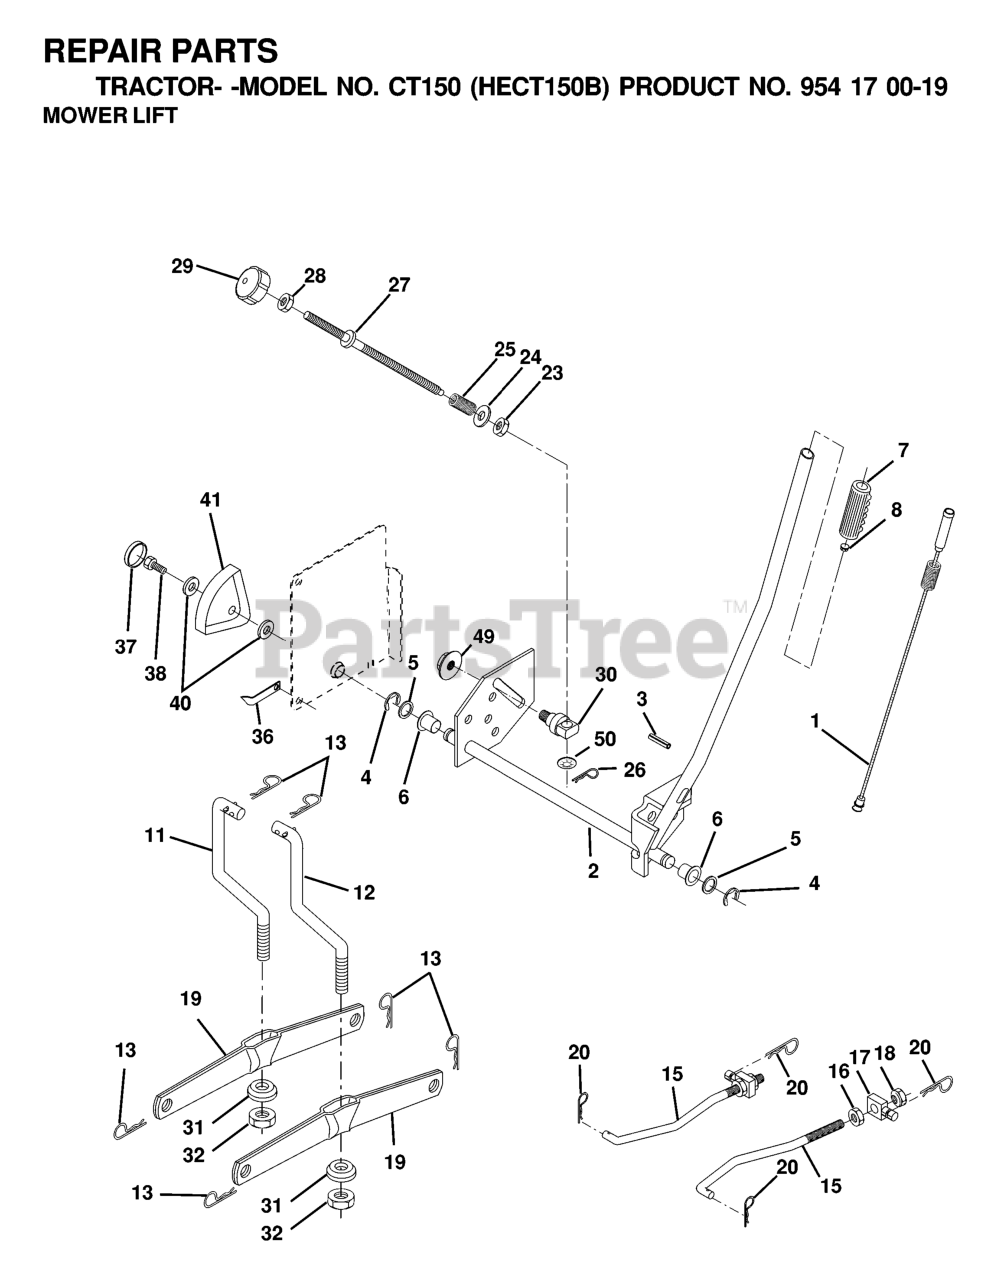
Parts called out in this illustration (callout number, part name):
1	WIRE ASM INNER W/ PLUNGER LT
2	SHAFT ASM R HANDLE
3	PIN GROOVE.
4	RETAINING RING LT
6	BEARING.NYLON
7	GRIP HANDLE
8	PLUNGER BUT KIT
11	LINK
12	LINK
13	RETAINER-SPRNG RB
15	LINK FRONT
16	NUT.HEX.JAM.1/2-13
17	TRUNION
18	NUT.LK.W/WSH.1/2.
19	ARM.REAR.SUSPENSION
20	SPRING RETAINER
25	SPRING**
26	RETAINER CLIP
27	ROD ADJ LIFT
28	NUT
29	KNOB INF 3/8-16
31	BEARING PIVOT
32	NUT CROWNLOCK 3/8-24
36	POINTER, HEIGHT INDICATOR(2 2)
38	SCREW 5/16-18X1
41	HEIGHT INDICATOR
49	NUT
50	NUT PUSH M
51	RETAINER-SPRNG RB
